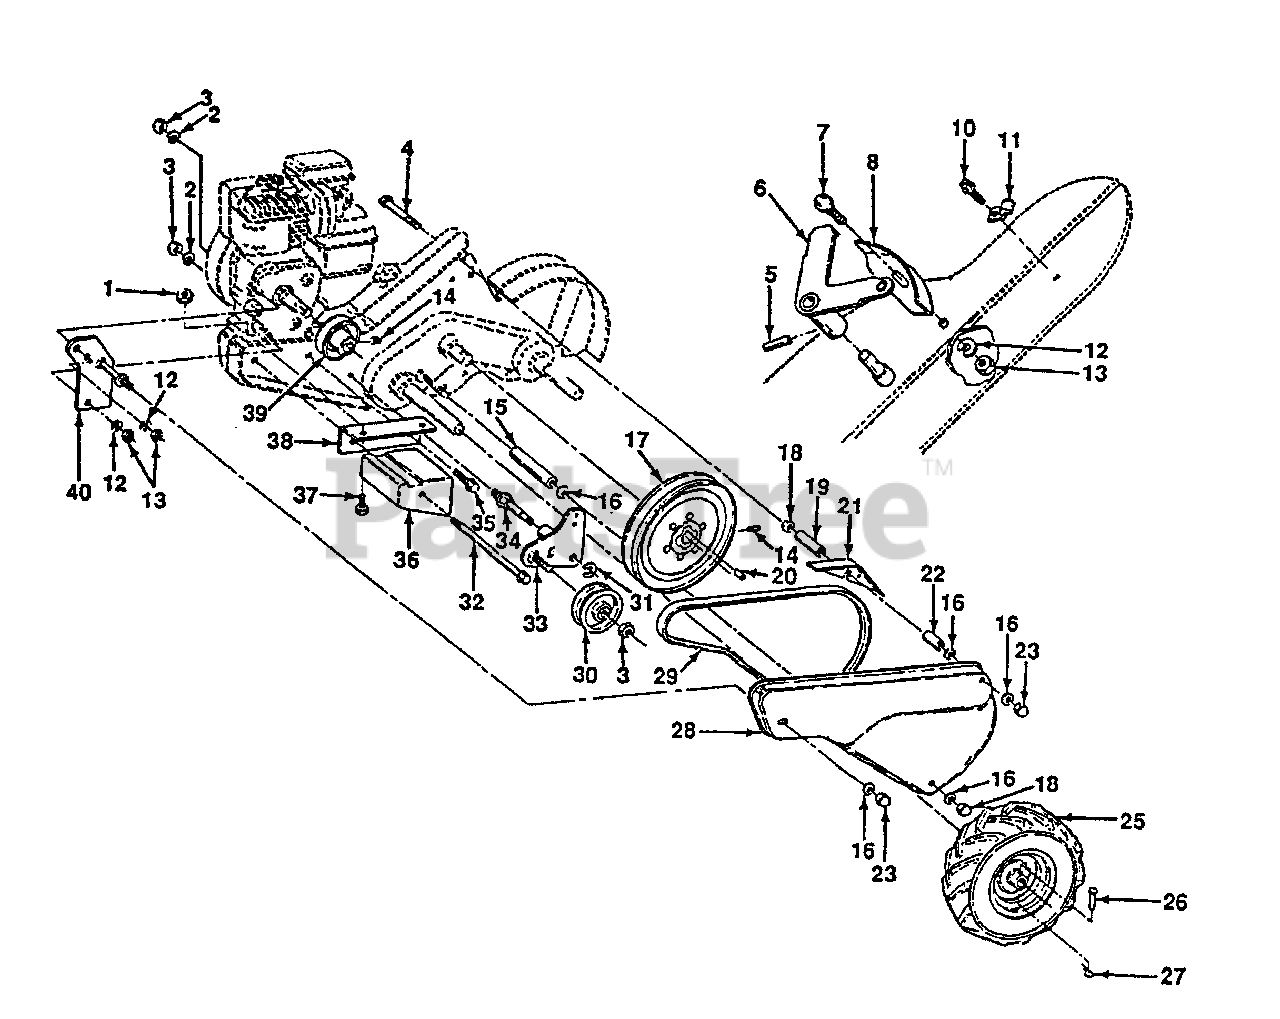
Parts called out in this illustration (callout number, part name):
1	Nut, Keps 5/16-18
2	Washer, Lock 3/8
3	Nut, Hex 3/8-16
4	Bolt, Hex 5/16-18 x 4-3/4
5	Pin, Roll
6	Lever, Shift
7	Bolt, Carriage 1/4-20 x 1/2 Gr. 5
8	Panel, Shift Indicator
10	Screw, Hex, Washer Head, Slotted #10-24 x 1/2
12	Washer, Lock 1/4
13	Nut, Hex 1/4-20
14	Screw, Set Hex 5/16-18 x 3/8
15	Spacer, Split 0.327 x 0.42 x 2.68
16	Washer 11/32 x 11/16 x 16 Ga.
17	Sheave, Transmission
18	Nut, Hex 5/16-18
19	Spacer, Split 0.327 x 0.42 x 1.75
20	Key, Square 3/16 x 1-1/8
21	Guard, Pinch Point
22	Spacer, Split 0.327 x 0.42 x 2.09
23	Nut, Cap 5/16-18
25	Tire Valve
26	Rivet, Drilled
27	Clip, Hairpin
28	Guard, Belt
29	Belt, V
30	Pulley, Idler
31	Ring, Klip
32	Bolt, Hex 5/16-16 x 12
33	Bracket, Idler
34	Shaft, Idler Arm
35	Bolt, Hex 3/8-16 x 1
36	Counterweight, L. H.
37	Bolt, Hex 5/16-18 x 1-1/2
38	Bracket, Reinforcement, L. H.
39	Sheave, Engine
40	Bracket, Guard Belt
40	Decal, Shift Indicator
40	Decal, Belt Guard
